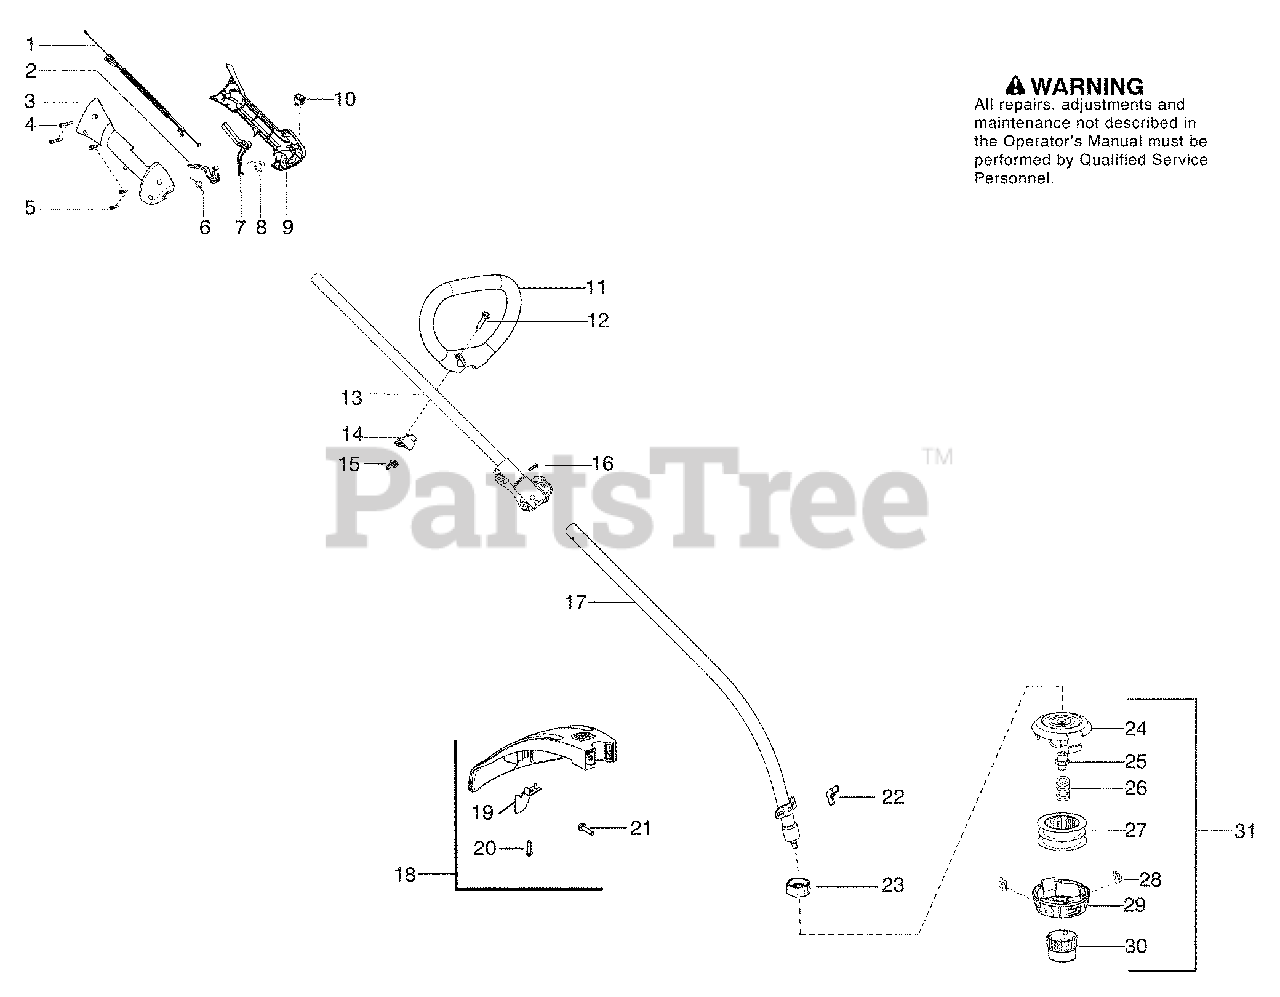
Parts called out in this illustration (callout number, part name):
1	Assy - Cable/Wire Harness
3	Housing - Throttle (RH)
6	Spring - Trigger
7	Lockout - Throttle
8	Spring - Lockout
9	Housing - Throttle (LH)
10	Kit - Switch
11	Handle - Assist
13	Kit - Driveshaft Upper
14	Clamp - Assist Handle
15	Wingnut
17	Kit - Lower Shaft
18	Kit - Shield
19	Limiter - Line
22	Wingnut
27	Assy - Wound Spool
28	Eyelet
29	Cover
31	Assy. - TNG7 Cutting Head
